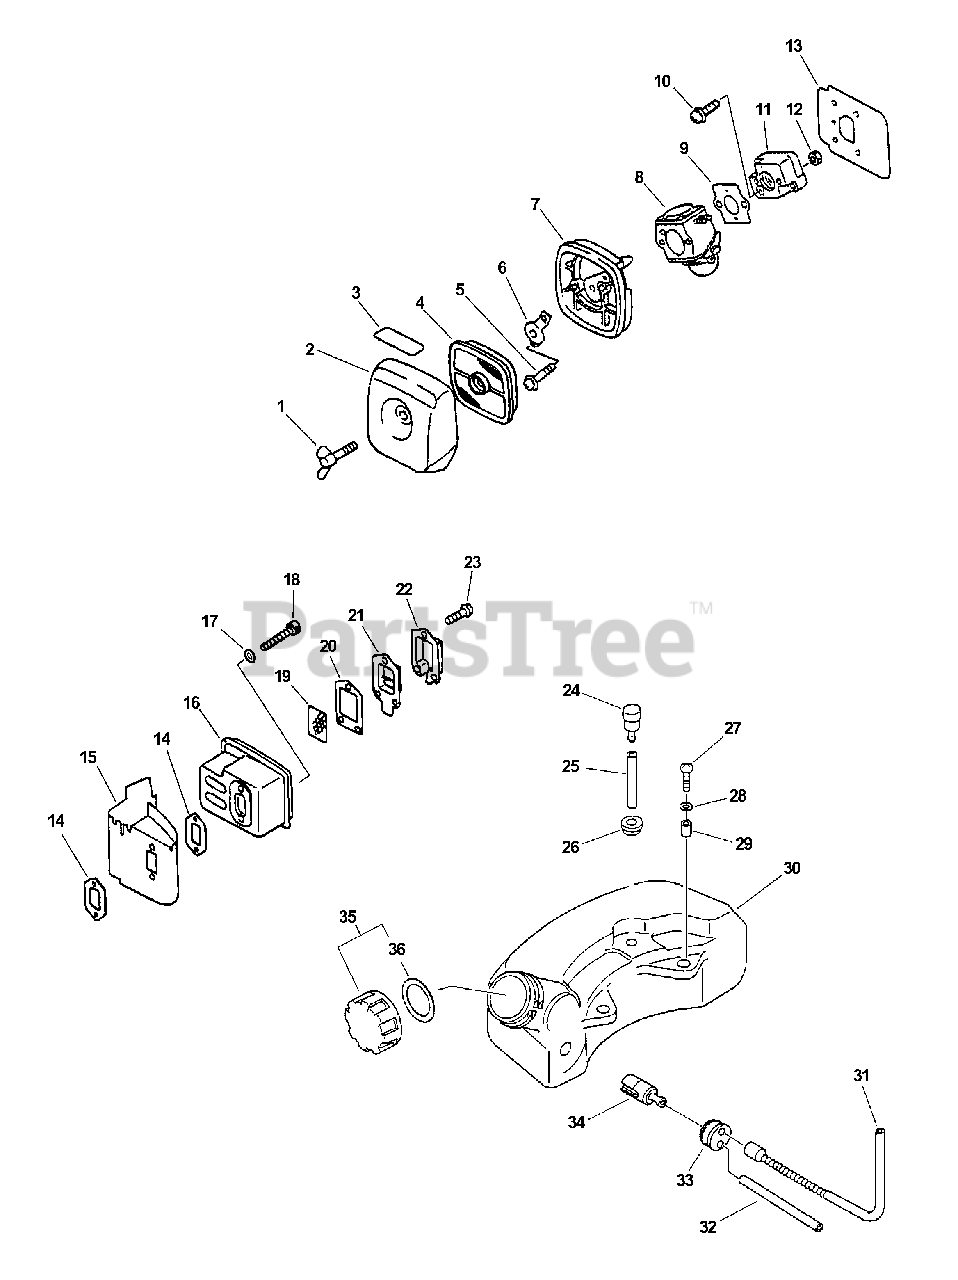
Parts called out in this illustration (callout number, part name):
1	BOLT, WING 5×20
2	COVER, AIR FILTER - GRAY
3	LABEL, CHOKE
4	FILTER, AIR - SINGLE LAYER
5	SCREW 5×65
6	PLATE, PREVENT
7	AIR FILTER CASE ASSY
8	CARBURETOR - C1U-K51
9	GASKET, INTAKE
10	SCREW 5×20
11	INSULATOR, INTAKE
12	NUT M5
13	HEAT SHIELD, INTAKE
14	GASKET, EXHAUST
15	COVER, EXHAUST
17	WASHER, FLAT 5.5×10×0.8
18	BOLT 5×55
19	SCREEN, SPARK ARRESTER
20	GASKET, EXHAUST
21	GUIDE, EXHAUST
22	GUIDE, EXHAUST - INNER
23	SCREW 4×10
24	VENT ASSY
25	PIPE, FUEL
26	GROMMET
27	SCREW 5×16
28	WASHER 5.5×12×0.8
29	SPACER 6.2×7.8×6
30	TANK, FUEL
31	PIPE, FUEL
32	PIPE, FUEL RETURN 3×6×110
33	GROMMET, FUEL
34	FILTER, FUEL
35	CAP ASSY, FUEL
36	GASKET, FUEL CAP
